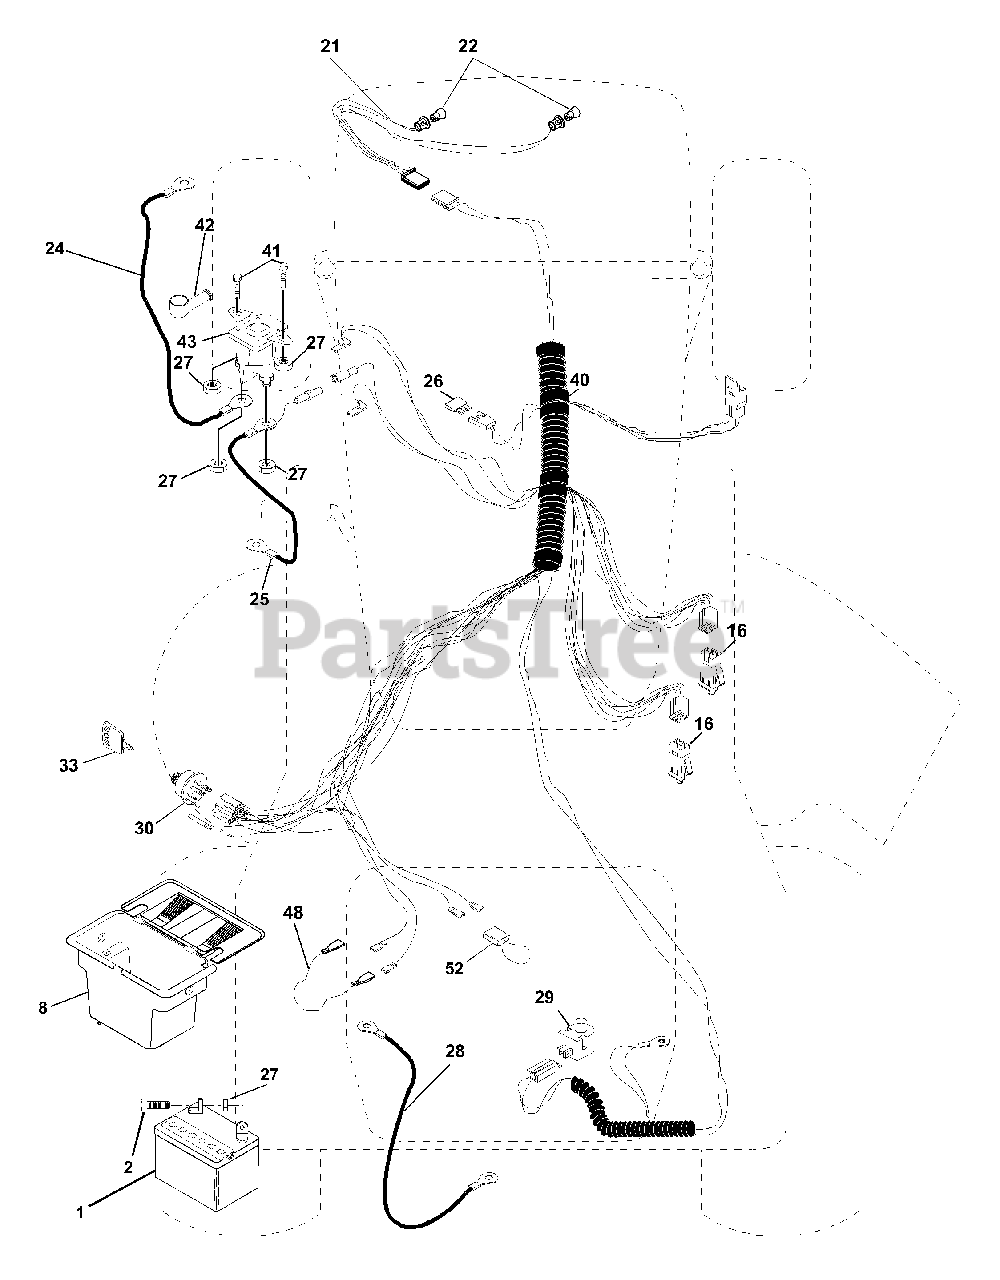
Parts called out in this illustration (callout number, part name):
1	Battery 12 Volt 25 Amp
2	Bolt Hex Hd 1/4-20unc X 3/4
8	Case Battery Mech Hiinge
16	Switch Interlock Push-In
21	Harness Asm Light W/4152j
22	Bulb Light #1156
24	Cable Battery 6 Ga 11"red
25	Cable Battery
26	Fuse 15 AMP
27	Nut Keps Hex 1/4-20 Unc
28	Cable Ground 6 Ga 12"black
29	Switch Plunger Nc Gray
30	Switch Ign
33	Key Ign
40	Harness Ign
41	Bolt Blk Fin Hex 1/4-20
42	Cover Terminal Red
43	Solenoid
48	Adapter Ammeter
52	Protection Wire Loop
